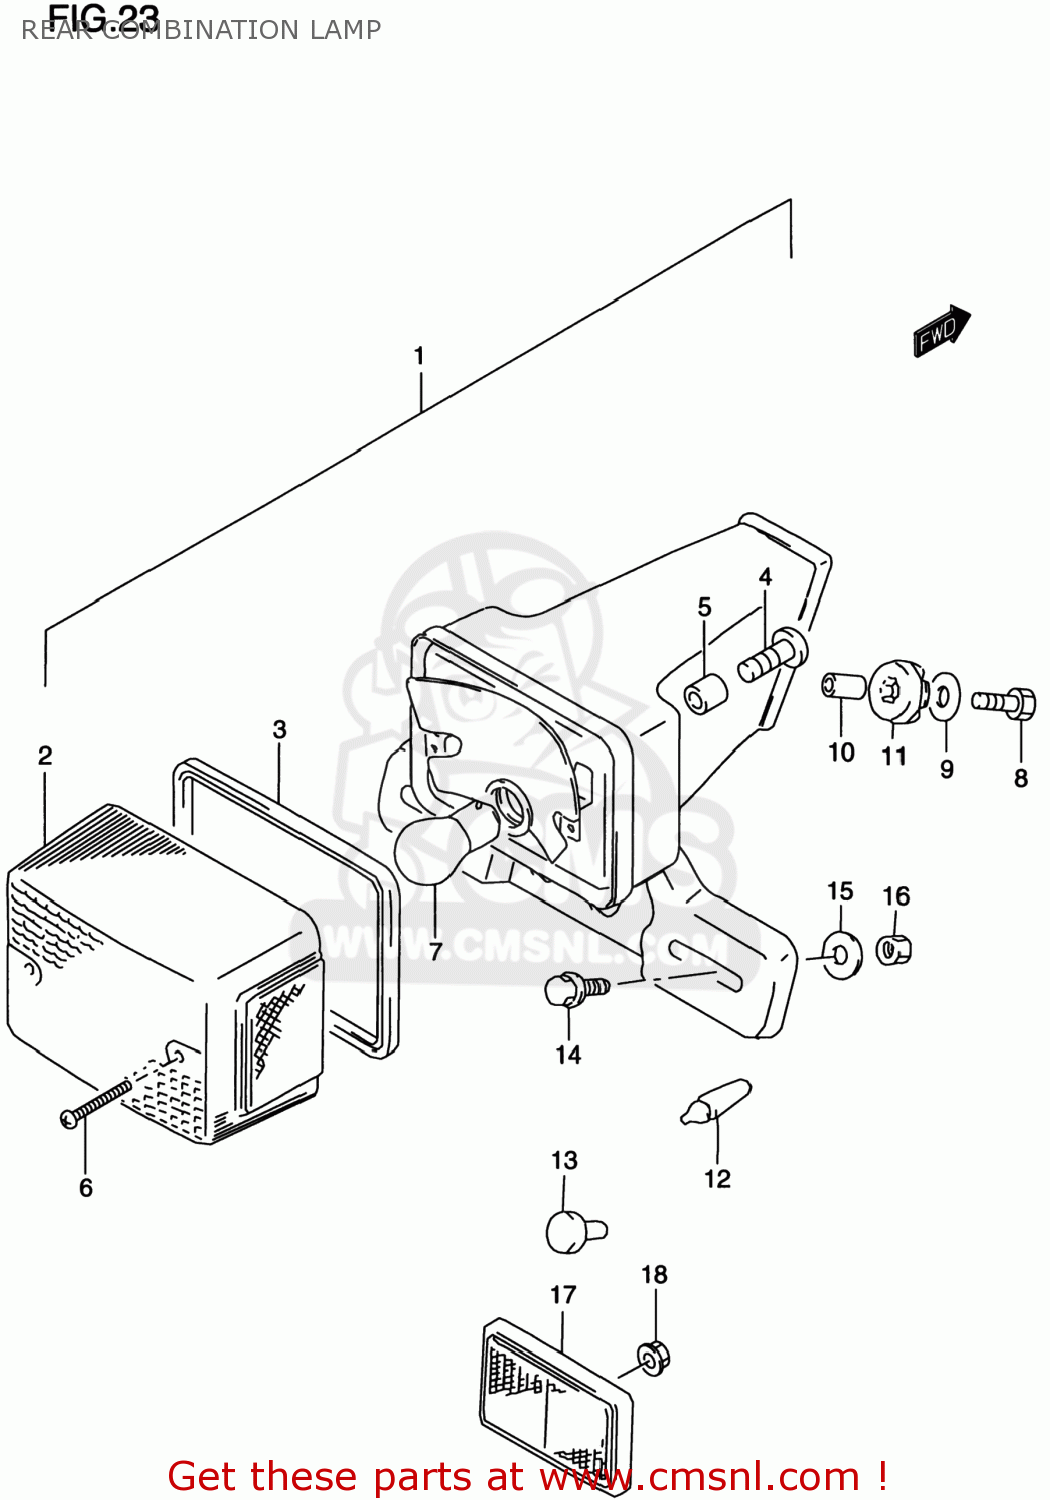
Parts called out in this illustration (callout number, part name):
1	LAMP ASSY,RR COMBINATION
2	LENS
3	GASKET,LENS (NAS)
4	SCREW(6X25)
5	SPACER
6	SCREW(4X45)
7	BULB(12V21/5W)
8	BOLT
9	WASHER
10	SPACER(6.5X10X13)
11	CUSHION
12	CUSHION
13	CUSHION
14	BOLT
15	WASHER
16	NUT 6MM
17	REFLECTOR ASSY,RR
18	NUT
